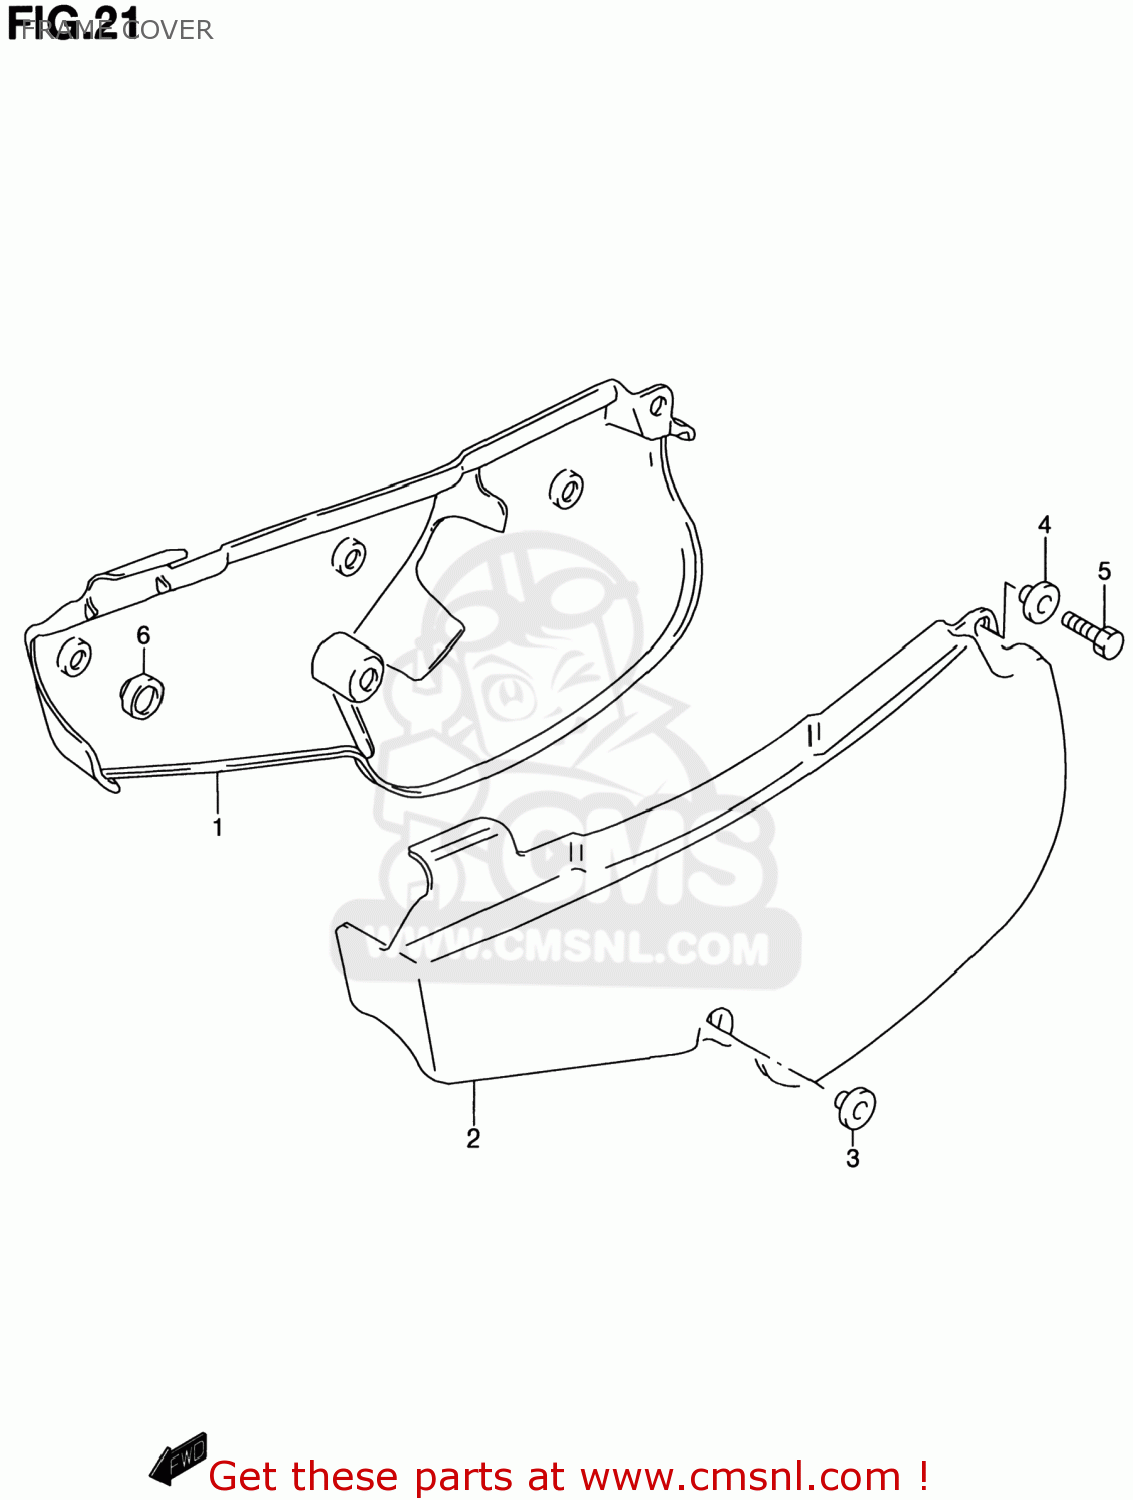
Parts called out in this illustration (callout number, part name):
1	COVER,SIDE,R
2	COVER,SIDE,L
3	WASHER
4	WASHER(6.5X20X1.6)
5	BOLT
6	CUSHION
